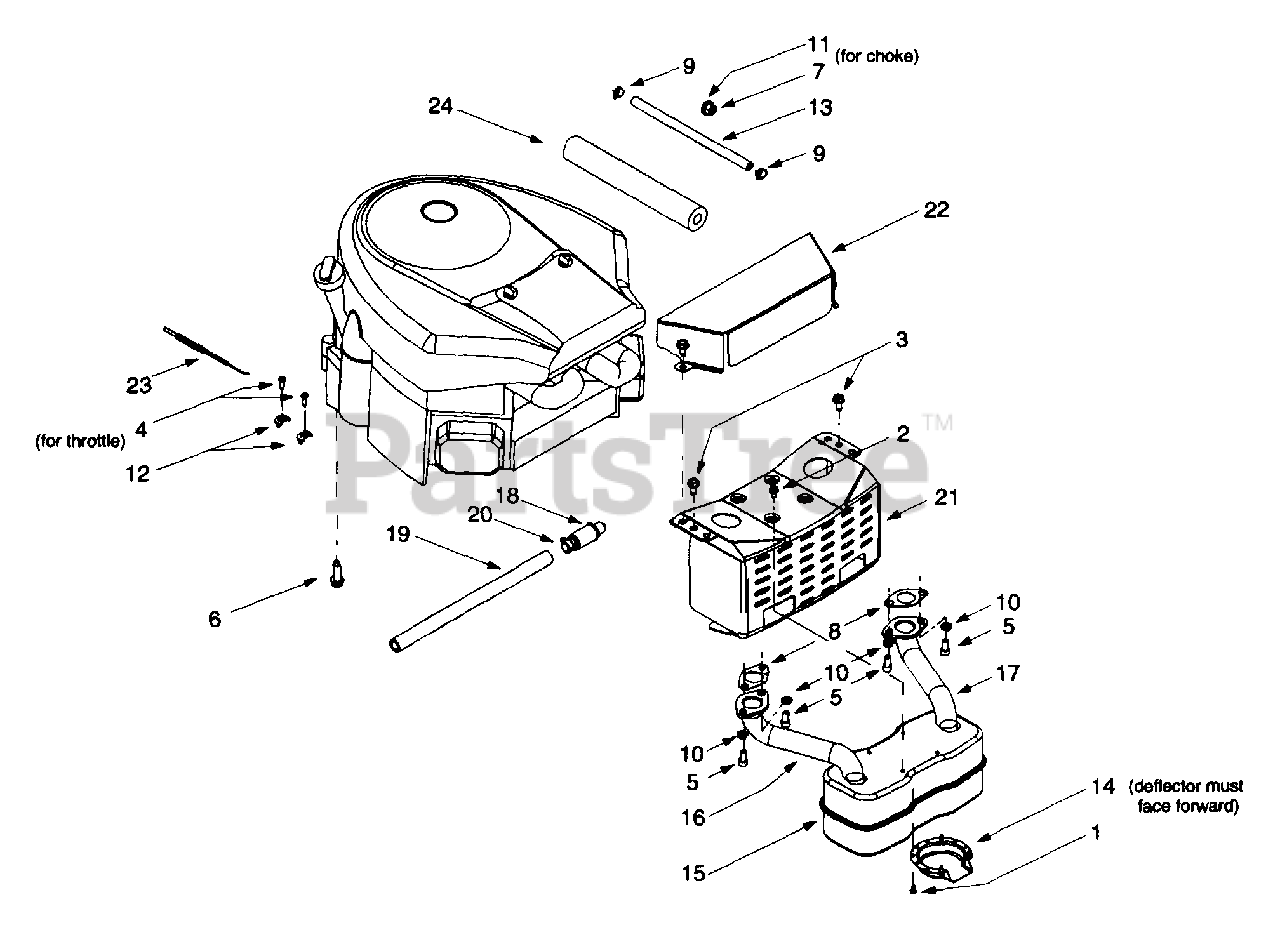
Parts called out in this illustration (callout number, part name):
1	Self Tapping Screw, #8-32 x .375
2	Self Tapping Screw, 1/4-20 x .5
3	Self Tapping Screw, 5/16-18 x .625
4	Screw, #10-32 x .625
5	Socket Cap Screw, 5/16-18 x .625
6	Self Tapping Screw, 3/8-16 x 1.25
7	Hex Nut, 3/8-16
8	Exhaust Gasket
9	Hose Clamp
10	Lock Washer, 5/16
11	Flat Washer, .406 x .875 x .059
12	Casing Clamp
13	Fuel Line Hose
14	Muffler Deflector
15	Muffler
16	RH Exhaust Pipe
17	LH Exhaust Pipe
18	Oil Drain Valve
19	Oil Drain Hose
20	Oil Drain Cap
22	Engine Heat Shield
23	Throttle Cable
24	Foam
